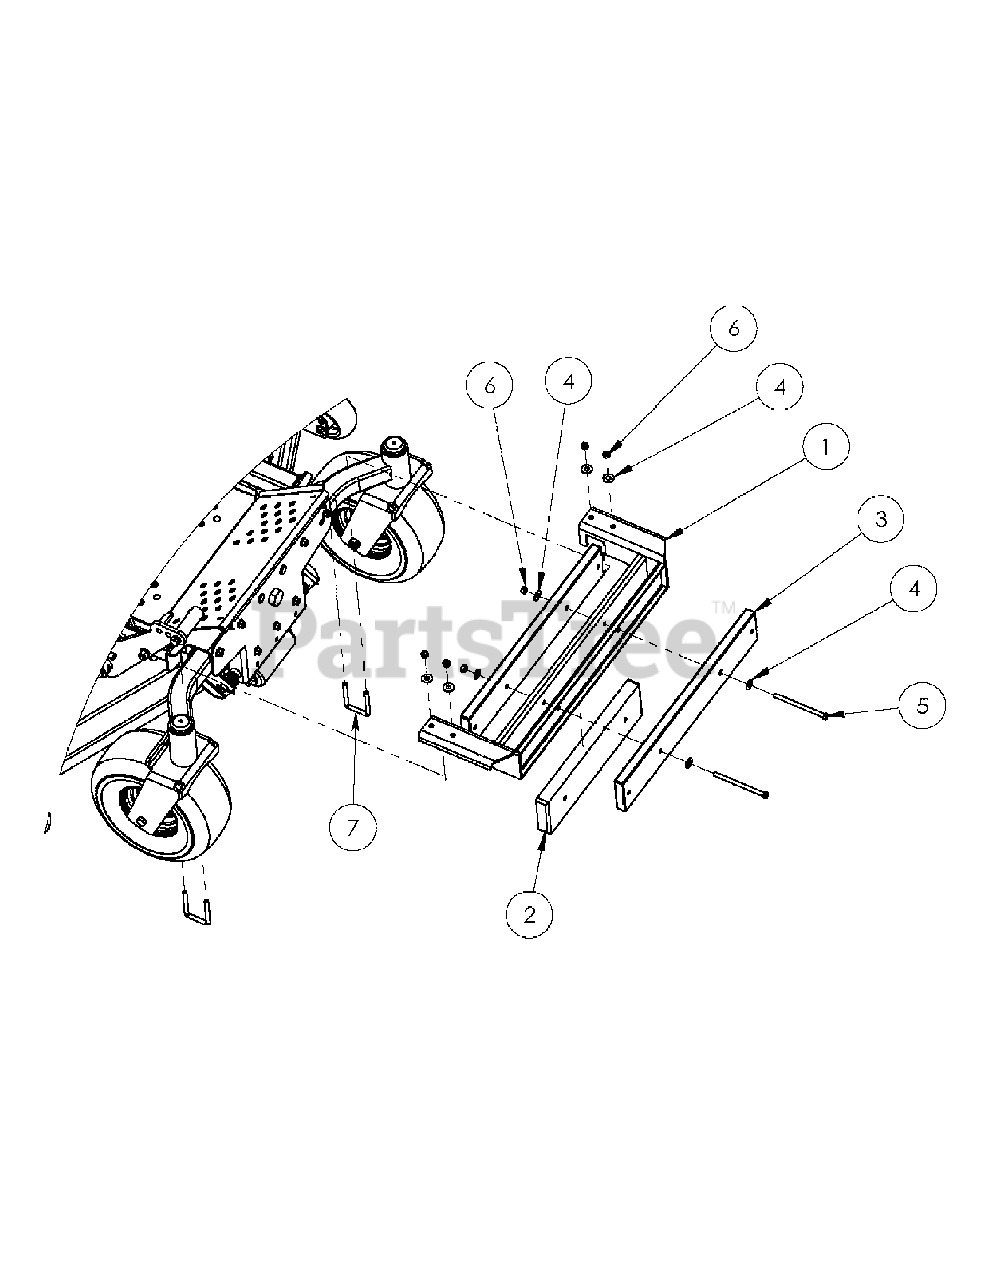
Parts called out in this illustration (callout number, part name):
1	WEIGHT BRACKET
2	BAR WEIGHT
3	EXISTING WEIGHT FROM REAR OF MOWER
4	3/8" FLAT WASHER
5	CAP SCREW 3/8-16 X 5 1/2" LONG
6	HEX NUT, NYLON INSERT-3/8"-16
